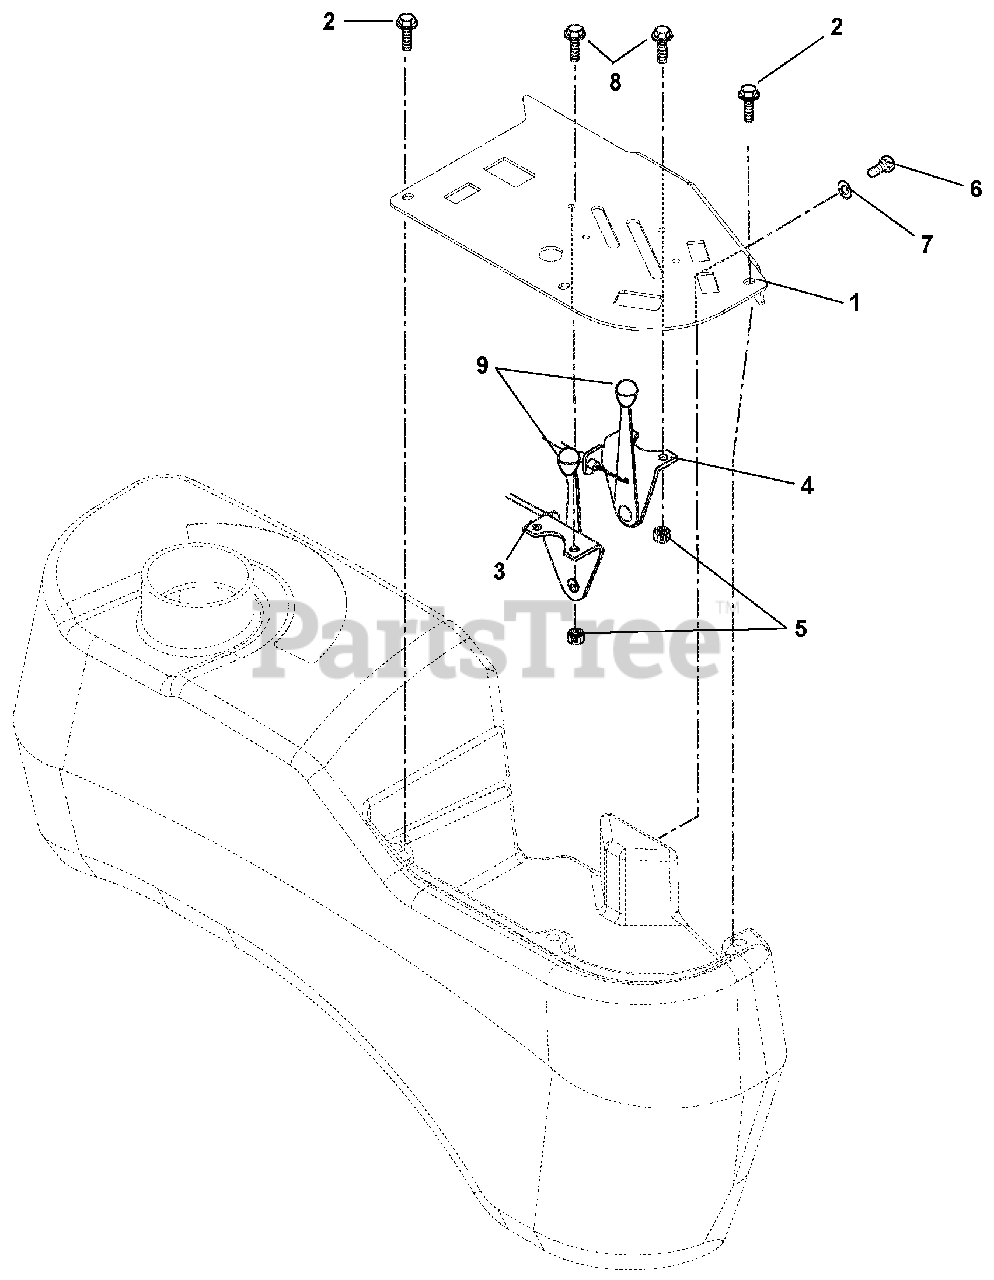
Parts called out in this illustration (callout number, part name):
1	Panel, Control
2	Screw, Machine Hex Washer Head 10-24 x .38 Stainless
3	Throttle, Control
4	Choke Control
5	Nut, Locking Nyloc 10-24 With Insert
6	Bolt, Hex .31-18 x .75 Grade 5
7	Washer, Flat Steel .38 x .875 x .083
8	Screw, Machine Hex Washer Head 10-24 x .50
9	Knob, Control Black .38-16 x .62
